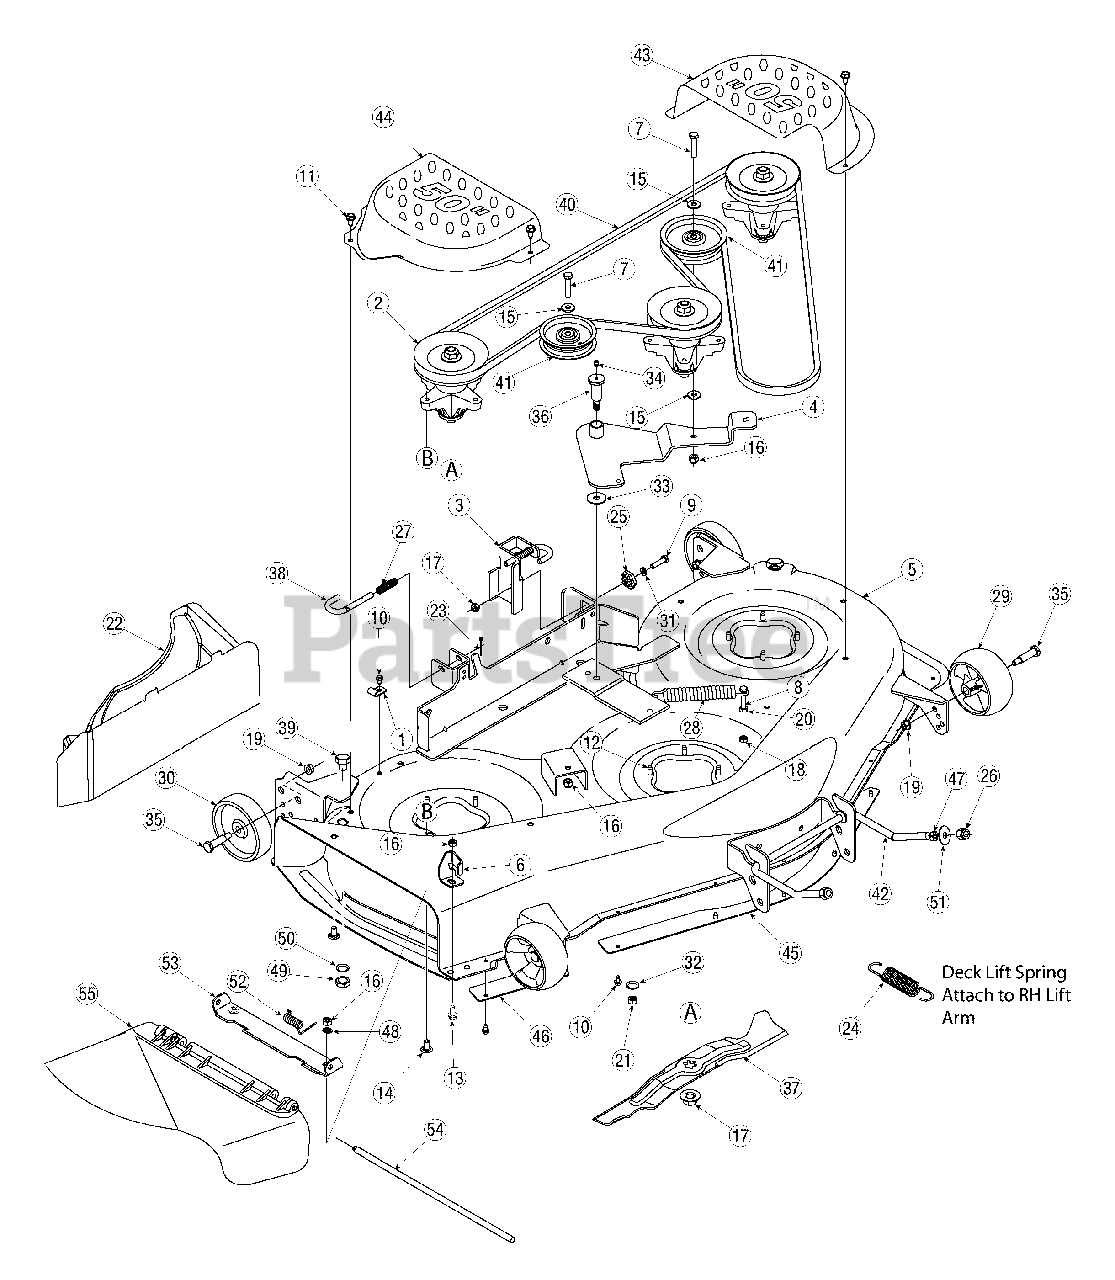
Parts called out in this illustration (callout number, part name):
1	Hook, Retainer
2	Spindle Assembly
7	Screw, 3/8-16, 1.75
8	Screw, 5/16-18 x 2.00
9	Screw, 5/16-18, 1.25, Gr5
10	Screw, 1/4-20 x 0.5
11	Screw, 5/16-18 x.500
12	Screw, 5/16-18 x.75
13	Screw, Carriage, 3/8-16 x 1.0
14	Screw, Carriage, 3/8-16 x.75
15	Washer, Flat,.406 x.875 x.059
16	Nut, Nylon Lock, 3/8-16
17	Nut, Hex, Lock, 5/16-18
18	Nut, Nylon Lock, 5/16-18
19	Nut, Flange Lock, 3/8-16
20	Nut, Hex, 5/16-18, Gr5
21	Nut, 7/16-14
22	Mulch Plug
23	Pin, Cotter, 1/8 x 1.25
24	Extension Spring, 1.15 Dia. x 5.99 Lg.
25	Deck Adjustment Gear
26	Lock Nut, Hex, 1/2-13, Nylon
27	Spring, Compression,.531 x 1.75
28	Spring, Extension,.94 x 6.74
29	Deck Wheel, 5.0
30	Deck Wheel, 5.0
31	Washer, Lock, 5/16, Regular Duty
32	Washer, Bell,.45 x 1.0 x.062
33	Washer, Flat,.442 x 1.38 x.060
34	Fitting, Lube, 3/16
35	Shoulder Screw
36	Screw, Shoulder,.68 x 1.59
38	Rod, Handle, Deck Release.375 Dia
39	Screw Plug, M16 x 1.5
40	Belt, V-Type, Aramid
41	Pulley, Idler, 3.5"
42	Rod, Deck Adjustment
47	Hex Nut, 1/2-13
48	Push Nut, 3/8
49	Hex Nut, M16-1.5
50	Lock Washer, 5/8
51	Flat Washer,.51 x 1.12 x.06
52	Torsion Spring,.44ID x 2.10
53	Chute Bracket
54	Hinge Pin
55	Chute Deflector
